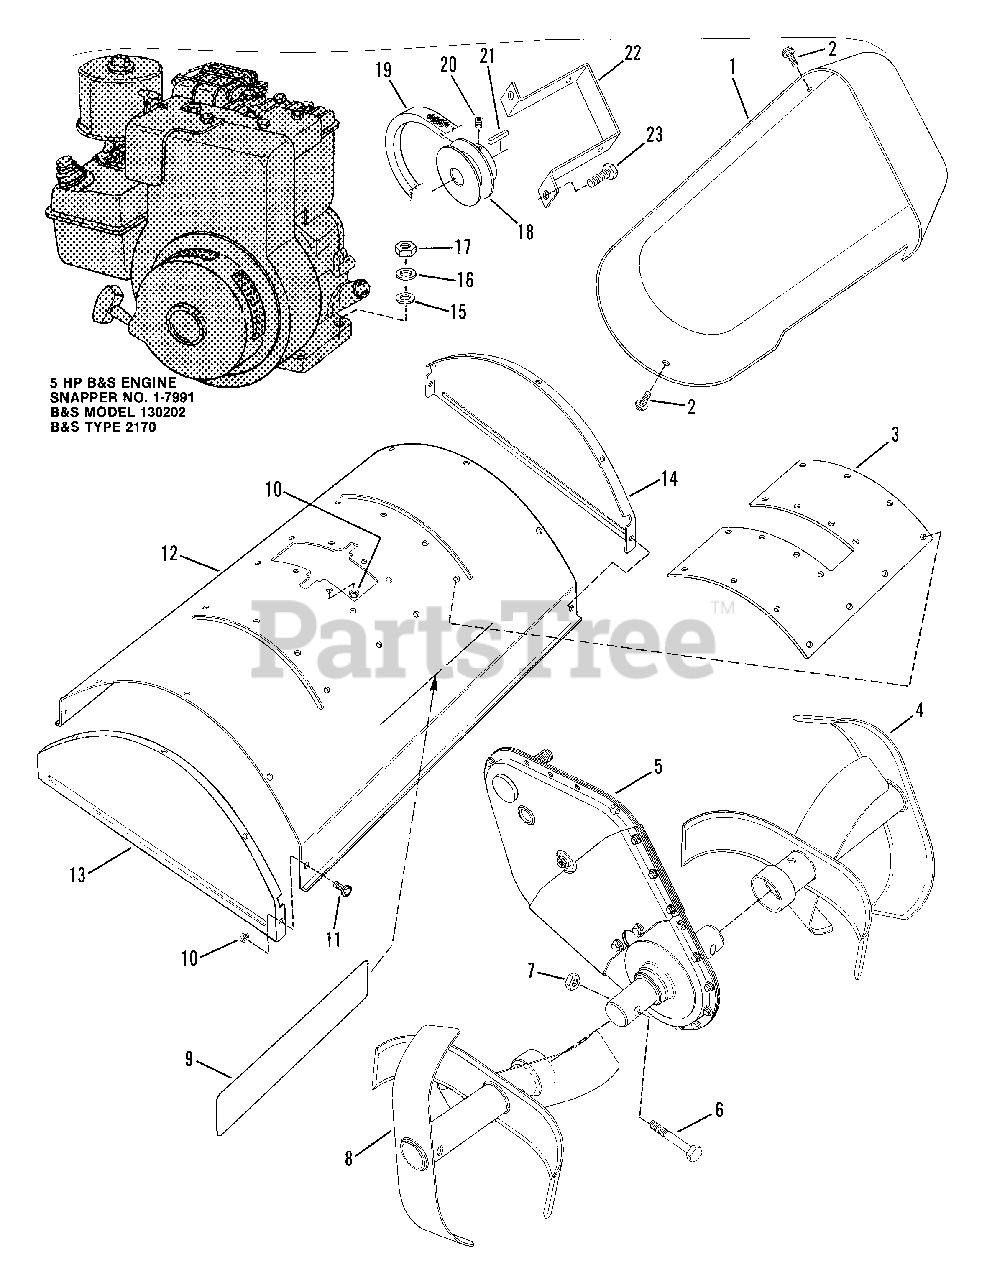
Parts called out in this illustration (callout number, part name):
1	COVER, Belt
2	SCREW, 1/4-20x3/8" H.W.H. Self-Tapping
3	PLATE, Reinforcing
4	TINE STRUCTURE, Right Side
5	CHAIN CASE ASSM'Y.
6	BOLT, 3/8-24x2 1/4" Shear
7	NUT, 3/8-24 Hex Center Lock
8	TINE STRUCTURE, Left Side
9	DECAL, Snapper
10	NUT, 5/16-18 Hex Flange Lock
11	BOLT, 5/16-18x1/2" Carriage
12	COVER, Tines
13	PLATE, Left Side
14	PLATE, Right Side
15	WASHER, 5/16 Flat
16	WASHER, 5/16 Lock
17	NUT, 5/16-18
18	PULLEY, Engine
19	BELT
20	SETSCREW, 5/16
21	KEY, 3/16x3/16x1"
22	GUIDE, Belt
23	SCREW, 5/16-24x1/2" Hex Head Cap
